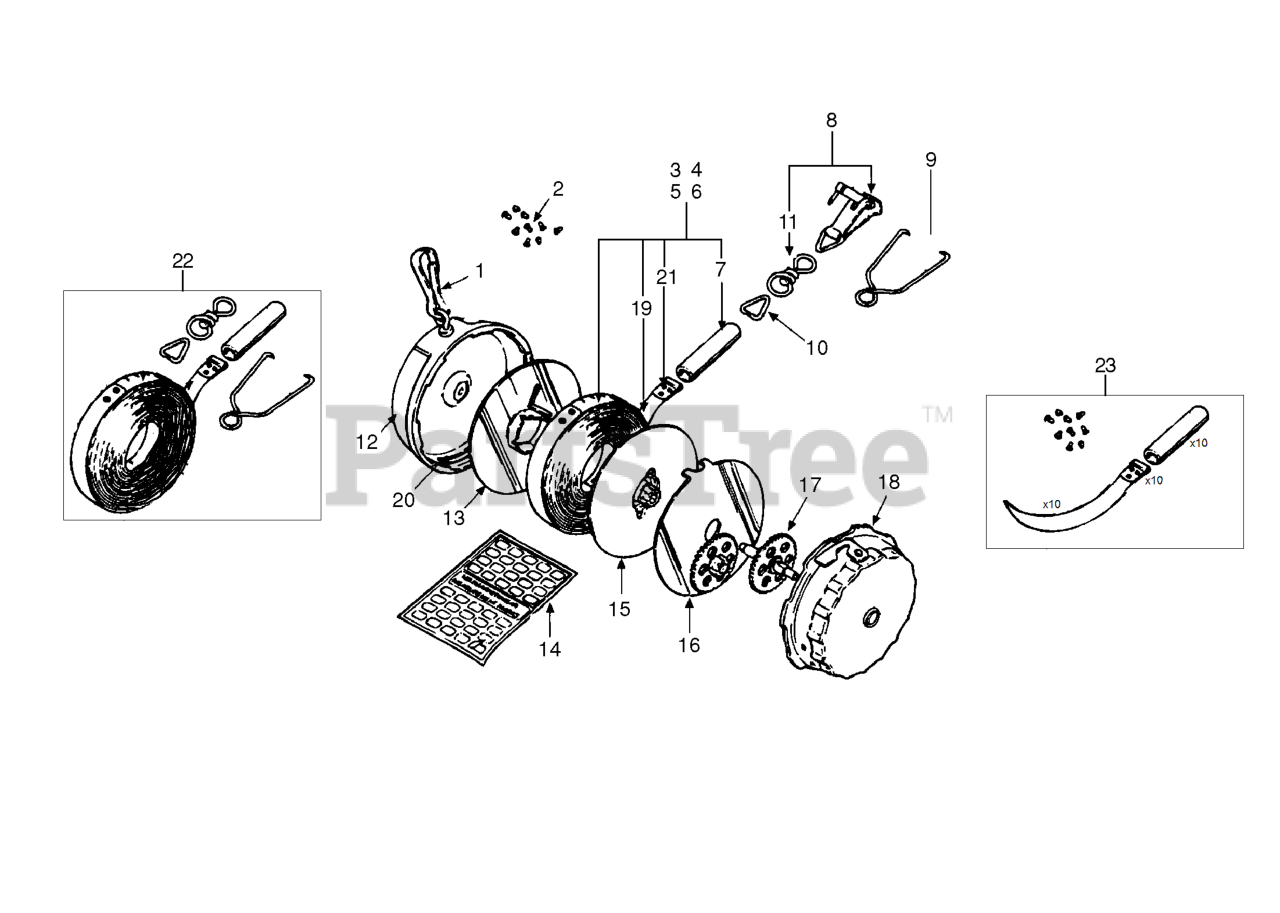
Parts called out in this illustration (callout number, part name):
1	SNAP HOOK
2	RIVET
3	SPARE TAPE 15/15
4	REPLACEMENT TAPE 20 M
5	SPARE TAPE 15/50
6	SPARE TAPE 20/66
7	TAPE MEASURE STOP
8	RELEASE HOOK
9	TAPE MEASURE HOOK
10	EYELET
11	TAPE MEASURE SWIVEL
12	TAPE MEASURE HOUSING
13	TAPE MEASURE TAPE ROLLER
14	TAPE MEASURE MARKING POINTS
15	TAPE MEASURE TAPE ROLLER
16	TAPE MEASURE COVER PLATE
17	TAPE MEASURE SHAFT GEAR
18	TAPE MEASURE SPRING HOUSING
19	TAPE MEASURE JOINING TAPE 25M
20	TAPE MEASURE ROLLER W/PIN
21	TAPE MEASURE PLATE
22	TAPE MEASURE TAPE 15M TIM HOOK
23	TAPE MEASURE JOINING TAPE
